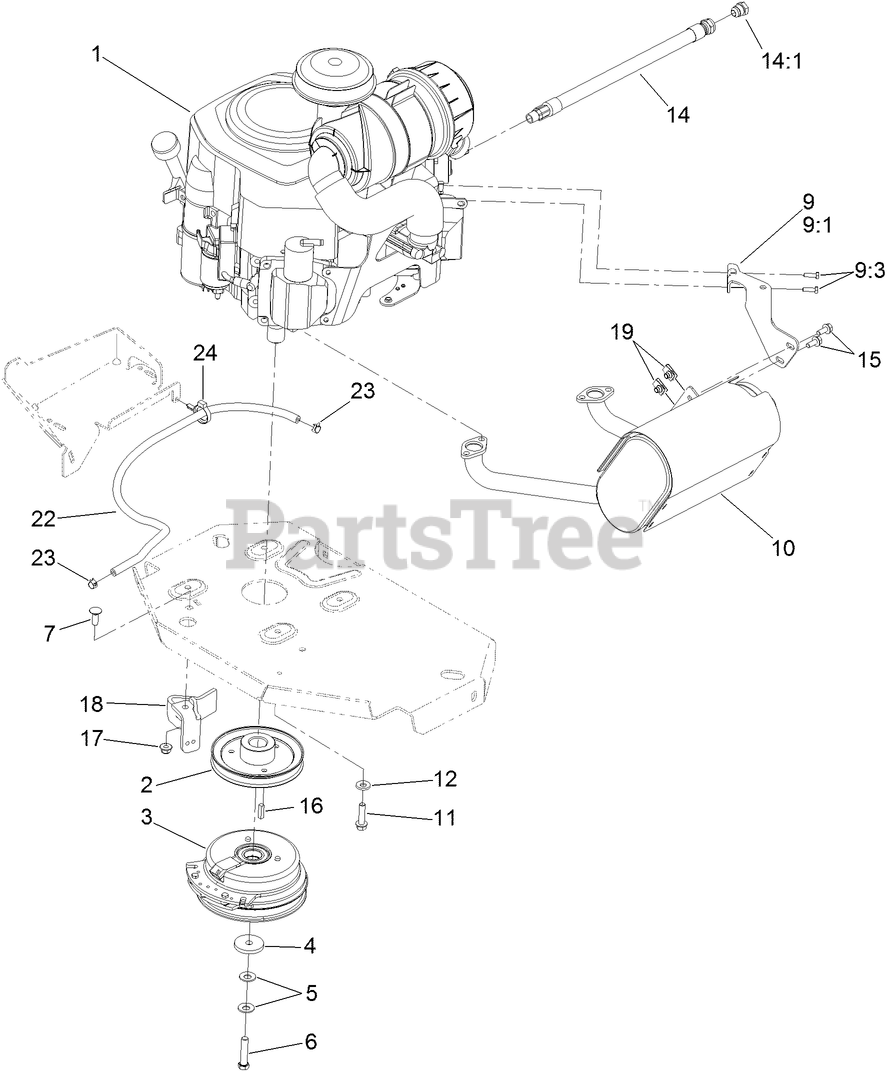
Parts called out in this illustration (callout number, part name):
2	SHEAVE
3	CLUTCH KIT
4	WASHER-CLUTCH
5	WASHER-SPRING
6	SCREW-HH W/LOCTITE
7	SCREW-CARR
9	MUFFLER BRACKET KIT
9:1	BRACKET-MUFFLER
9:3	SCREW-HH
10	MUFFLER
11	SCREW-HWH
12	WASHER-BELLEVILLE
14	OIL DRAIN HOSE ASM
15	SCREW-HHF
17	NUT-HF, NI
18	CLUTCH-ANCHOR
19	NUT-U
22	HOSE-FUEL
23	CLAMP-HOSE
24	CLAMP-HOSE
